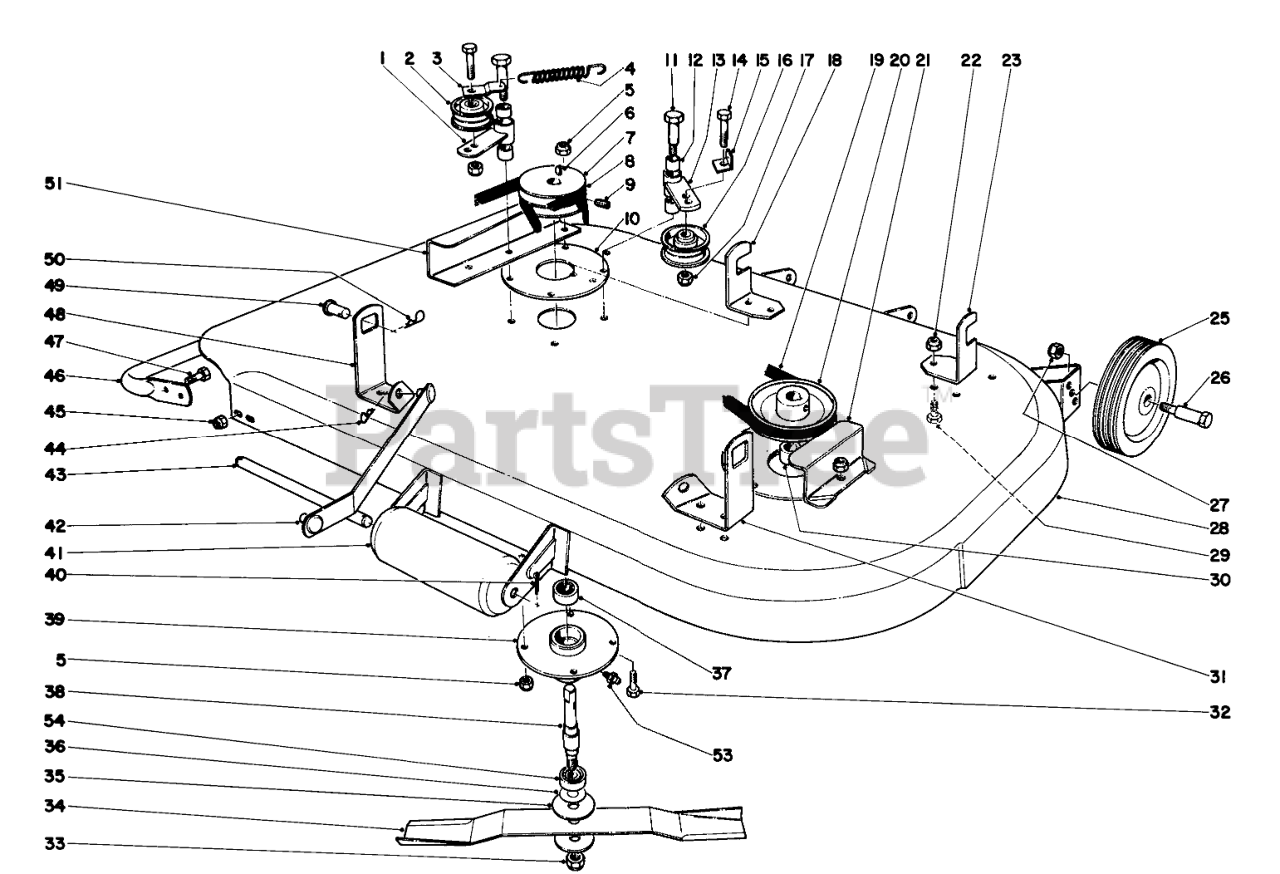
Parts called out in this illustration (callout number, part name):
1	Idler Plate Incl. Ref. #11
2	Flat Idler
4	Spring Tension
5	Nut
6	KEY-WOODRUFF
7	BLD SPDLE PULLEY (MACH)
8	Belt
9	SCREW-SET, HSH
10	Washer
11	SHOULDER BOLT
12	Bushing
13	Idler Plate
14	SCREW-HH
16	Pulley
18	Bracket
20	Pulley
21	Belt Guard
22	Nut
23	Bracket Mower
25	Wheel
28	Housing
29	SCREW-HH
30	Spacer
31	Bracket-Mower
32	SCREW-HH
34	Blade
35	WASHER
36	WASHER
37	Bearing
38	BLADE SPINDLE
39	Mower Spindle Housing
40	PIN-COTTER
41	Roller
42	Tow Bar
43	ROLLER SHAFT
44	PIN-COTTER
46	Mower Guard
47	SCREW-CARR
48	Bracket-Mower
50	PIN-COTTER
51	Guard Mower
53	FITTING-GREASE
54	.6693 RP BALL BEARING
